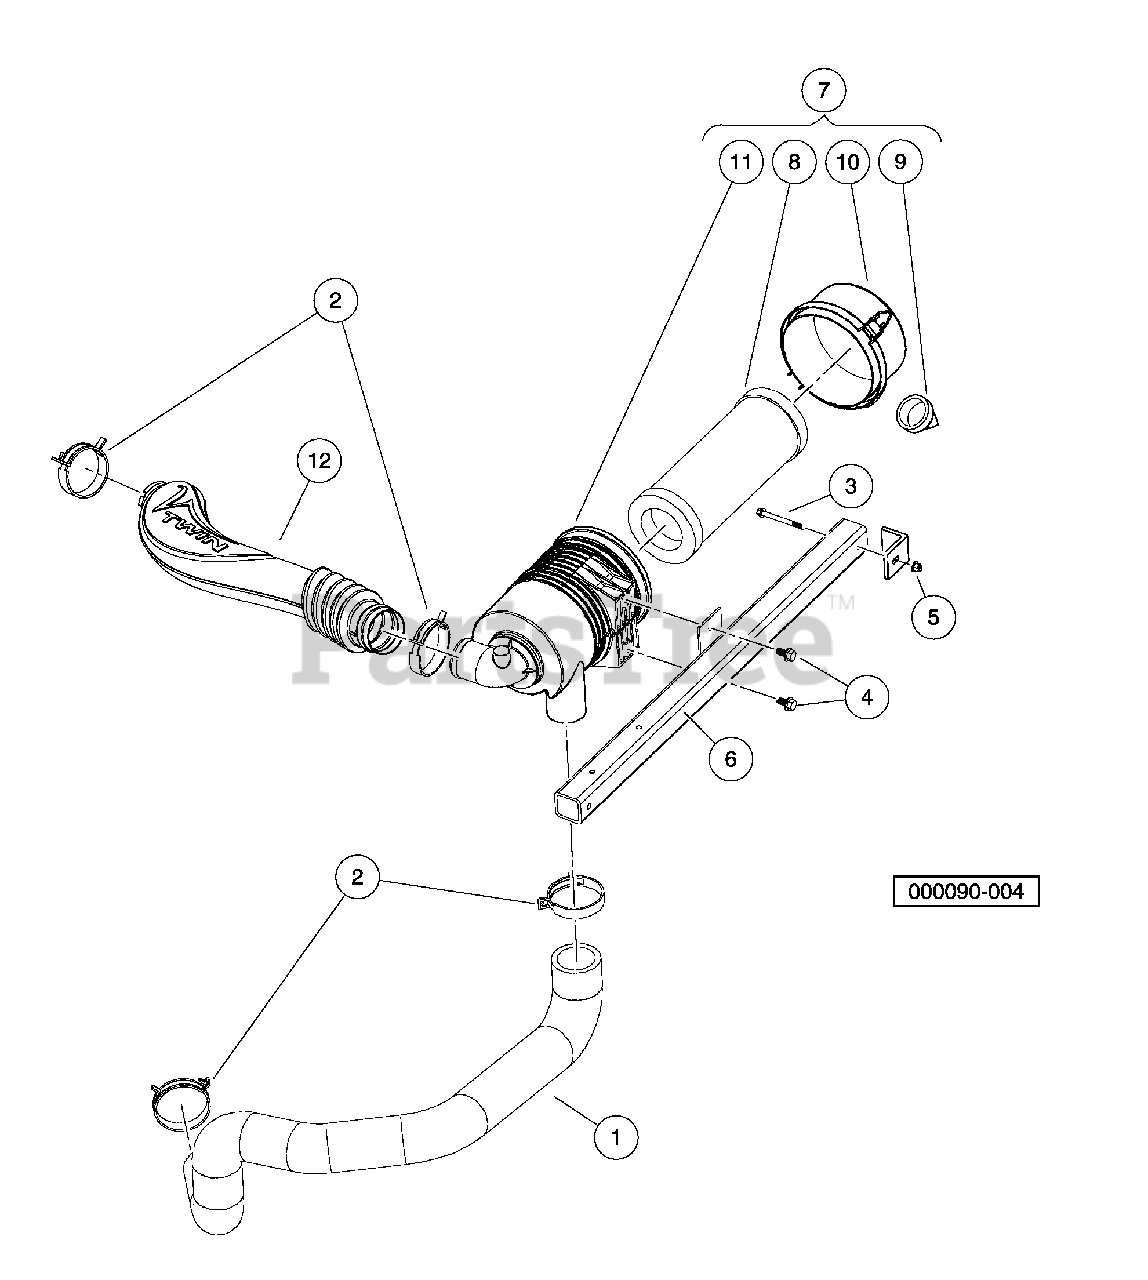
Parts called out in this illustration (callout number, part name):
1	Hose, Intake, Primary
2	Clamp, Hose, Ctb 64mm
3	Bolt, M 6 X 1.0 X 65 Hex, Flange, Head, Black.
4	Bolt Flanged Head, M8 X1.25x 16 with Loctite
5	Nut Flg, M6 X 1.0 Nylon
6	Weldment, Support, Air Cleaner
7	Filter, Air, Canister, W/labe
8	Element, Filter, Air, 5 In
9	Valve, Evacuator, Filter Air
10	Cap, Latch Lock, Filter, Air
11	Body, Canister, Filter, Air
12	Hose, Intake, Fh680d
